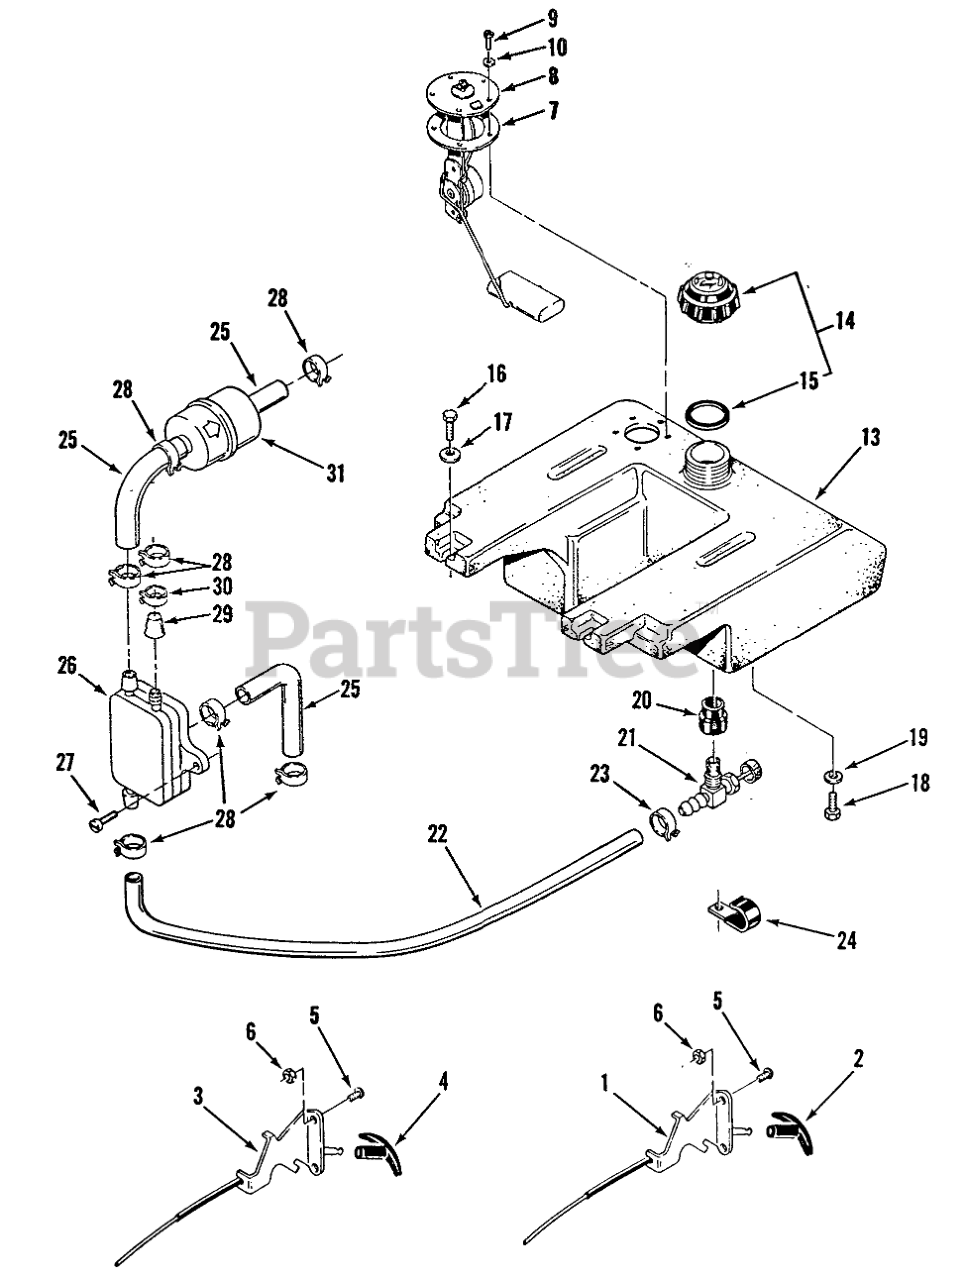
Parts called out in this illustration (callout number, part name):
1	Throttle Control
2	KNOB-THROTTLE
3	CONTROL-CHOKE
4	KNOB-CHOKE
5	SCRW-PHC
6	Nut
7	GASKET-SENDER, FUEL
8	SENDER-FUEL LEVEL
9	Screw
10	Lockwasher
13	Fuel Tank (includes items 20 & 21)
14	Fuel Cap (includes item 15)
15	GASKET-GAS CAP
16	Bolt
17	Washer
18	Bolt
19	Lockwasher
20	BUSHING
21	VALVE-FUEL
22	Line-Fuel 53"
23	Clamp
24	Clamp
25	Hose
26	Fuel Pump
27	Screw
28	Clamp
29	Cap
30	Clamp
31	X-REF 71-5960
